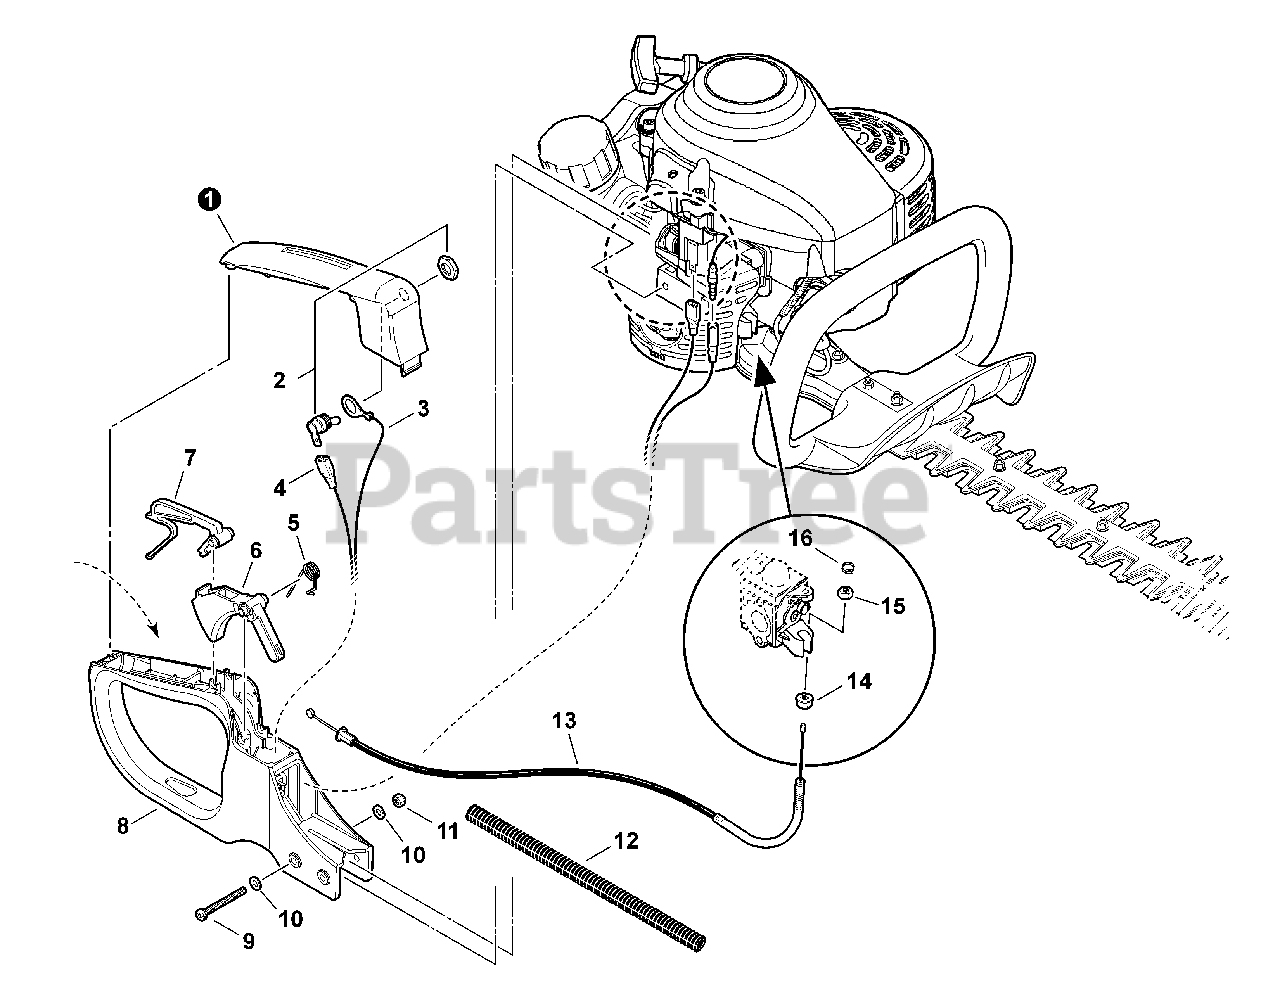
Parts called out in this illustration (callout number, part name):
1	COVER, HANDLE
2	IGNITION SWITCH ASSY
3	LEAD - GROUND
4	LEAD - IGNITION
5	SPRING, TRIGGER
6	TRIGGER, THROTTLE
7	LOCKOUT, THROTTLE
8	HANDLE - REAR
9	SCREW - 5×45
10	WASHER - 5
11	LOCKNUT - 5
12	TUBE, PROTECTIVE - CORRUGATED
13	CABLE, THROTTLE
14	NUT - 6 -- FLANGE
